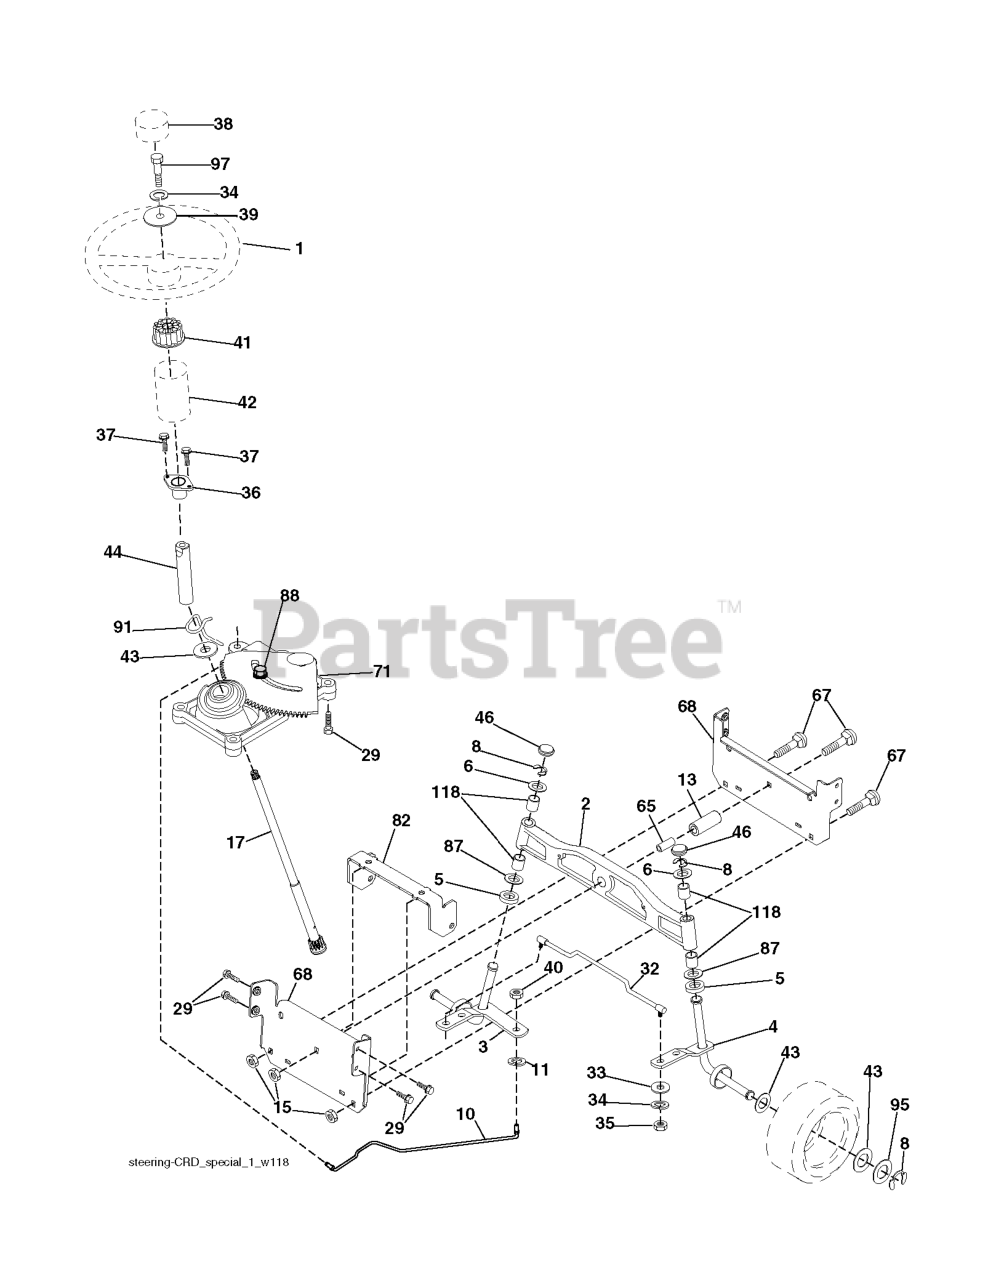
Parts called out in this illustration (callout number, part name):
1	RP WHEEL.STEER.HUSQ.PREM.OVMLD
2	AXLE ASSY FRONT
3	SPINDLE.ASM.LH.15"TIRES
4	SPINDLE.ASM.RH.15"TIRES
5	THRUST WASHER
10	DRAGLINK.15".TIRES.2001
11	WASHER, LOCK 3/8
13	TUBE, PIVOT AXLE
15	NUT
17	SHAFT STEERING SPLINE
29	SCREW, 3/8-16X3/4
32	TIE ROD
33	WASHER M
34	WASHER.LOCK.HVY.HLCL.SPR.5/16
35	NUT, CROWNLOCK
36	BUSHING, STEERING
37	SCREW.TT.#10-32X.5.3/8.FLANGE
38	RP INSERT.CAP.WHL.STRG.HUSQ.
39	WASHER.11/32
40	NUT CROWNLOCK 3/8-24
41	ADAPTER, WHEEL STNG..
42	BOOT, STEERING
44	SHAFT.EXTEN.STRG.SPLINE
46	CAP.SPINDLE.BLACK
65	SPACER BRACE AXLE
67	BOLT CARRIAGE
68	BRACE.AXLE.15"TIRES
71	STEERING ASM
82	BRACKET.SUSP.CHASSIS.FRONT.15
87	WASHER, FLAT .781 X 1 1/2"
88	BOLT, SHOULDER 7/16-20
91	CLIP.STEERING
95	WASHER.HARDENED
118	BUSHING, AXLE CAST
